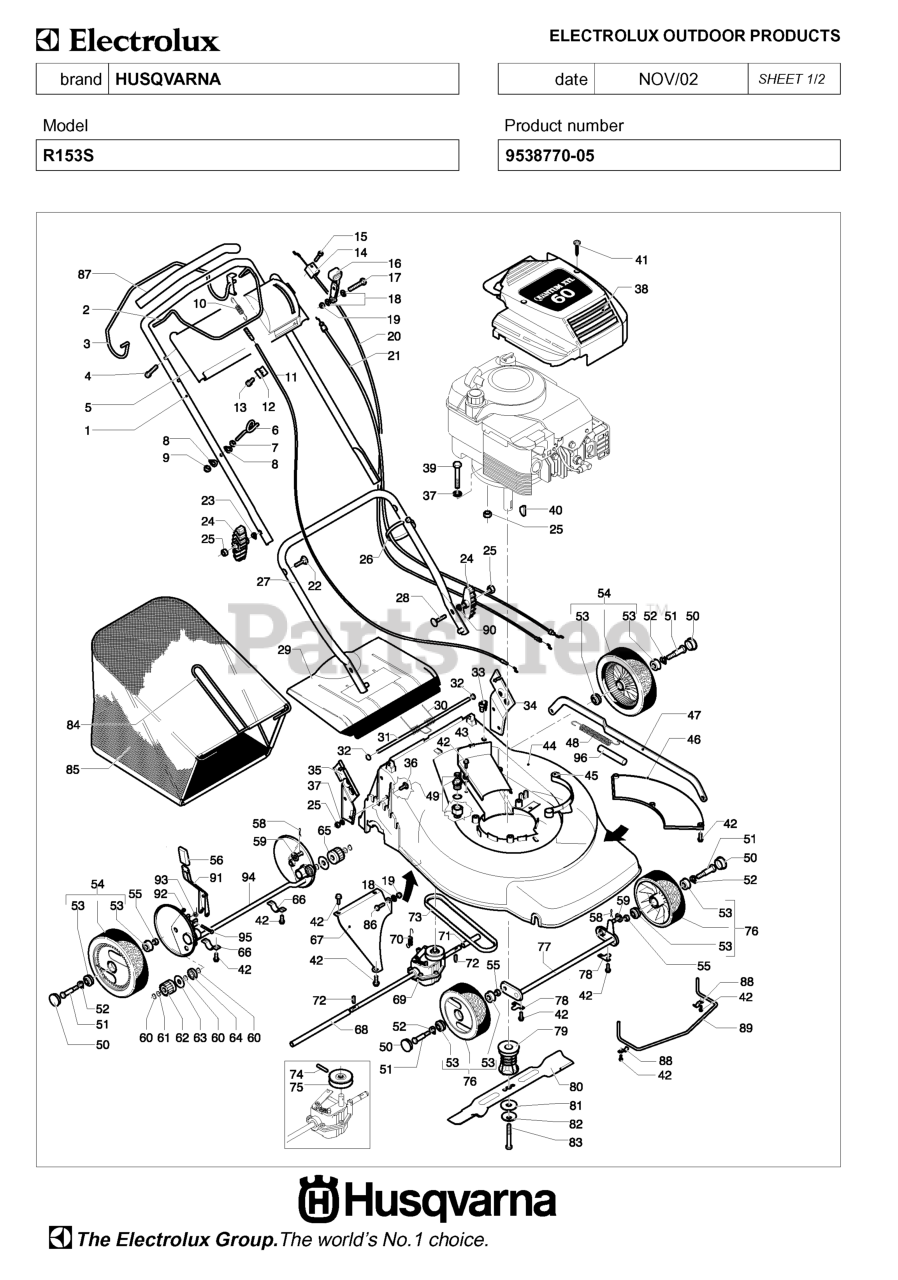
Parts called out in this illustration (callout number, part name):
28	Screws
42	Screws
58	Pins
60	Washers
